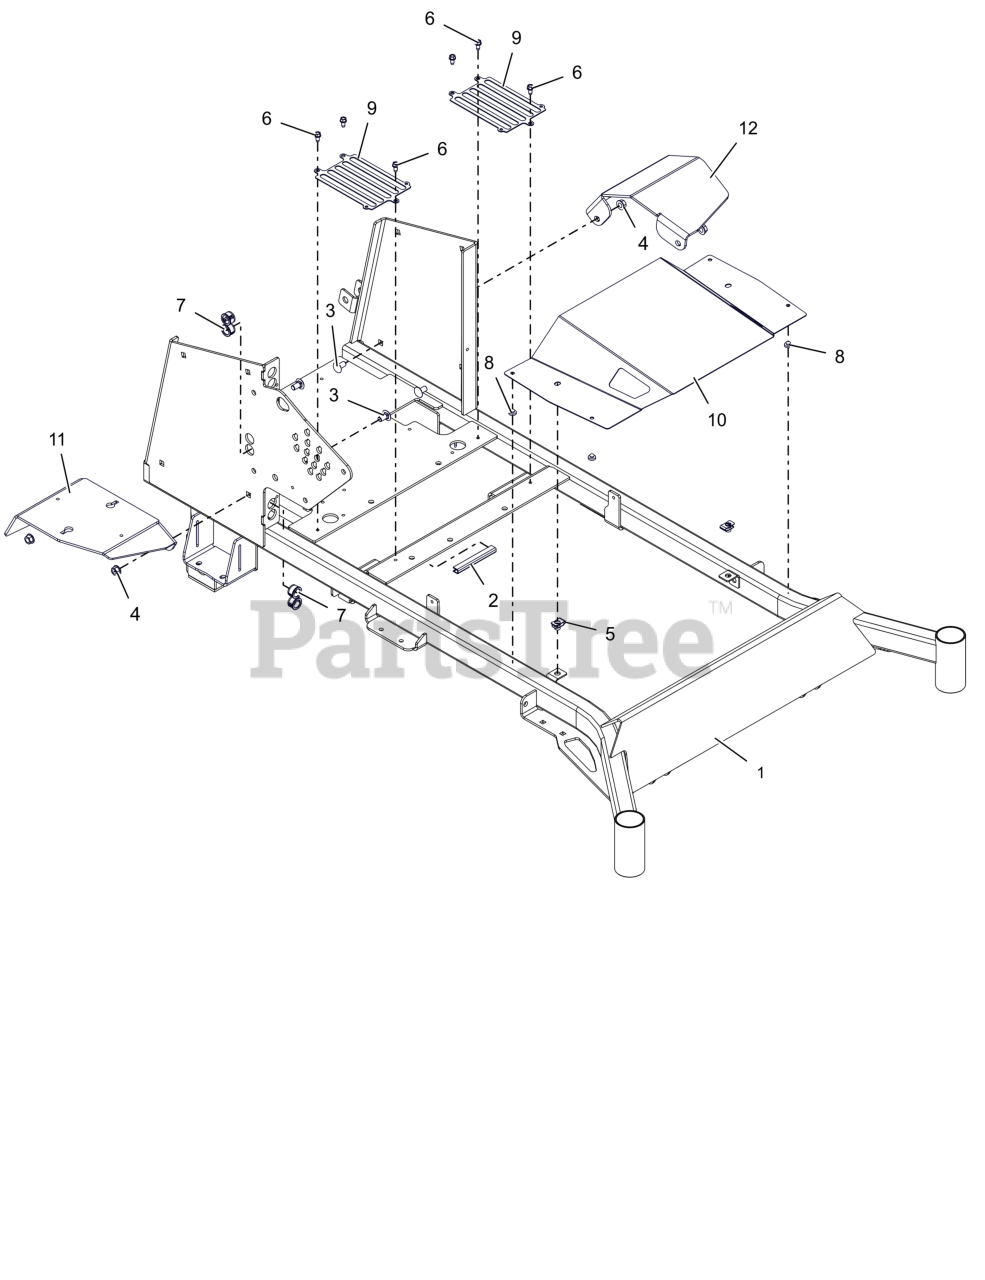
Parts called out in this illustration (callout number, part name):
1	WLDMT, RIDGELINE 48-52 FRAME (ORANGE)
2	STRIP, COWL
3	BLT, RHSSN .38-16X.75 G5 ZCC
4	NUT-LK-CTR-FLG .375-16 GF ZCC
5	NUT-CLIP RETAINER 5/16-18X.56
6	SCR-TAP .25-20X.50 HWH ZCC
7	BUSH, PANEL SNAP .687X.875X.56
8	BUMPER GROMMET
9	GUARD- FAN
10	BELT GUARD- 48/52"
11	FENDER- RH
12	FENDER- LH
